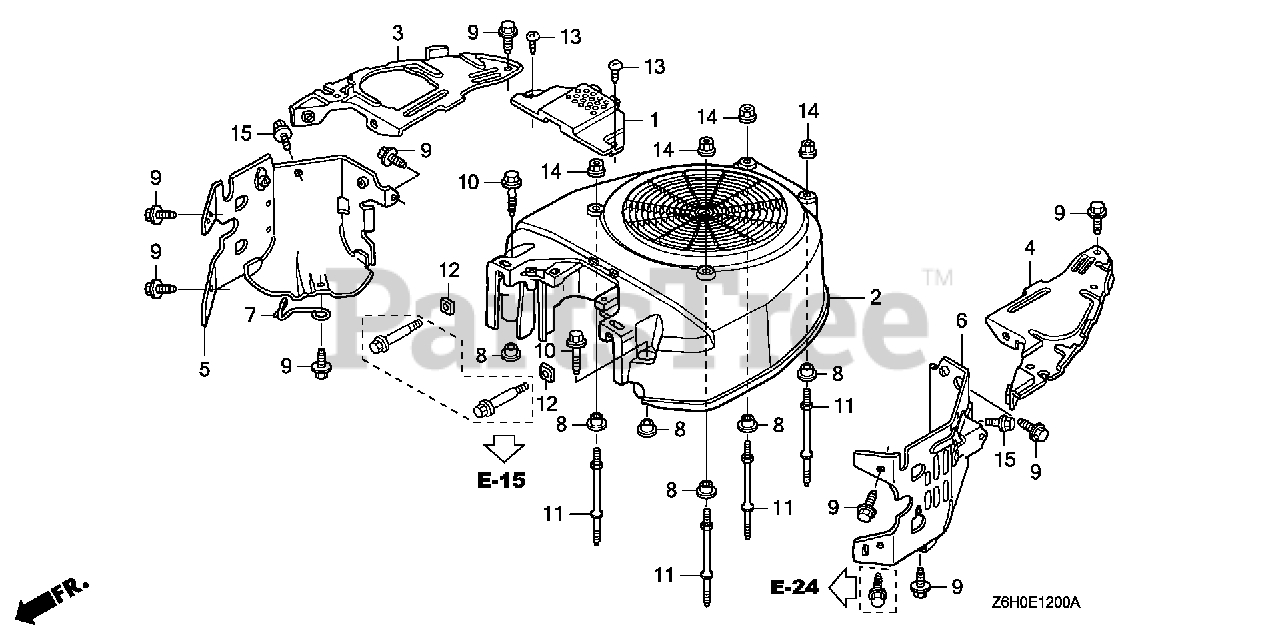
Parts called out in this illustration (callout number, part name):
1	COVER, FUEL PUMP
2	COVER, FAN *R280* (POWER RED)
2	COVER, FAN *NH1* (BLACK)
3	PLATE, SIDE
4	PLATE, SIDE
7	CLAMP, IGNITION TUBE
8	COLLAR B, TAILLIGHT
9	BOLT, FLANGE (6X12) (CT200)
10	BOLT, FLANGE (6X23) (CT200)
11	BOLT, STUD (6X71)
12	NUT, SQUARE (5MM)
13	SCREW, TAPPING (5X20)
14	NUT, FLANGE (6MM)
15	BOLT, FLANGE (6X8)
